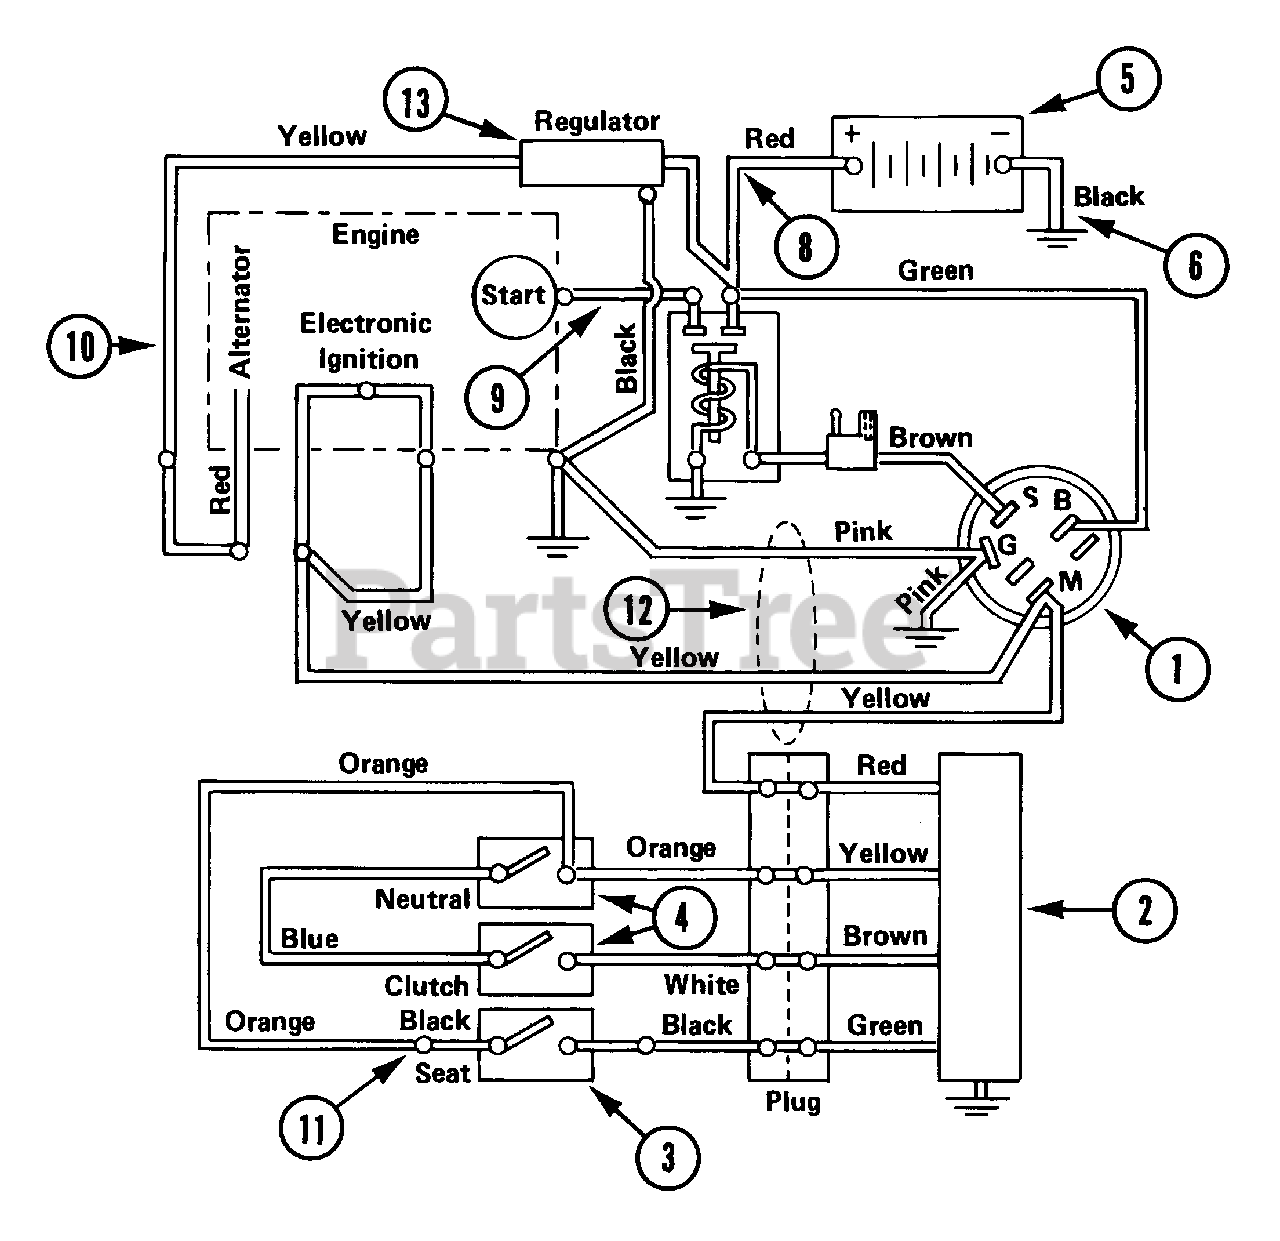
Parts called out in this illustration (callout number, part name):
1	IGNITION SWITCH ASSEMBLY
2	MODULE
3	SAFETY SWITCH
4	SWITCH INTERLOCK
5	BATTERY
6	GROUND CABLE .25X13.00X.31
8	STARTER CABLE 16"
9	STARTER CABLE 13"
11	ADAPTER - SEAT SWITCH
12	WIRE HARNESS
13	REGULATOR
